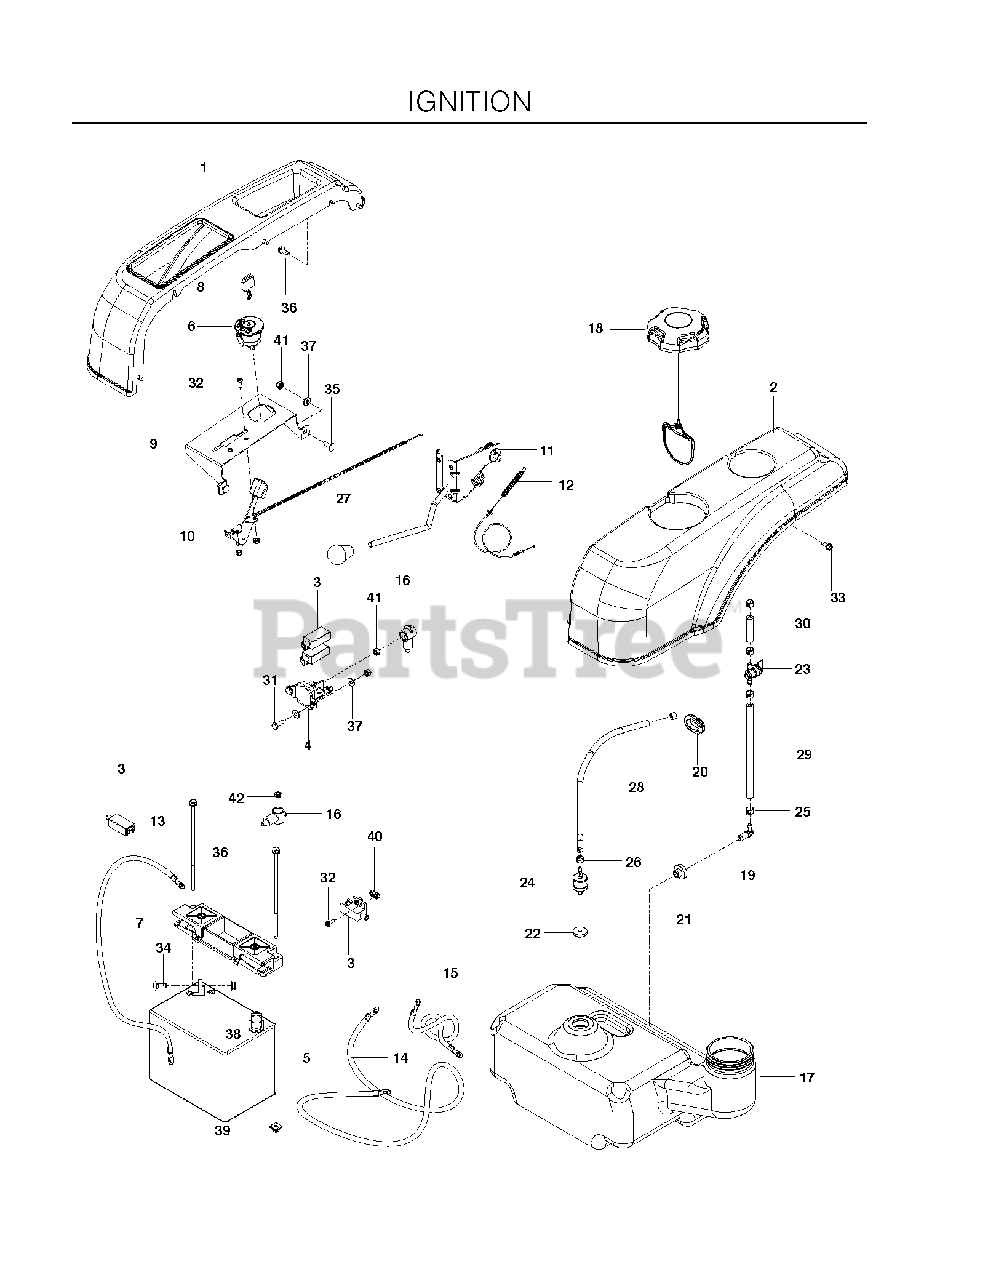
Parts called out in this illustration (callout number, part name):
1	FENDER RH
2	FENDER LH
4	SOLENOID
5	BATTERY, 12 V 330 AMP
6	IGNITION SWITCH
7	BATTERY HOLD DOWN
9	MOUNT, CONTROLS, BLK
10	THROTTLE CABLE
11	ASM, CLUTCH ENGAGE W/CABLE
12	CABLE, CLUTCH 38
13	BATTERY CABLE, NEGATIVE
14	POST.CABLE LONG
15	CABLE POSITIVE, LONG
16	TERMINAL COVER-SM
17	TANK, FUEL EPA
18	CAP, FUEL
20	RUBBER GROMMET
21	RUBBER GROMMET
22	GROMMET, CHECK VALVE
23	FUEL VALVE
24	VALVE, FUEL CHECK
25	HOSE CLAMP
26	CLAMP, HOSE
27	KNOB - SHIFT
28	HOSE, FUEL, 3/16" X 20"
29	HOSE 1/4 X 8
30	HOSE 1/4 X 2"
31	HCS 1/4C X 3/4 HCS
32	SCREW #10-24 X 5/8
33	SCREW 1/4 X 5/8
34	BOLT 5/16C X 3/4" CARRIAGE
35	RHSNB 1/4C X 3/4
36	BOLT - 1/4-20 X 7.5
37	WASHER 1/4 SAE
38	5/16-18 NYLOC FLANGE NUT
39	PUSH NUT-NYLON
40	NUT 10-24 NYLOC
41	NUT 1/4-20 NYLOC
42	JAM NUT 1/4C
